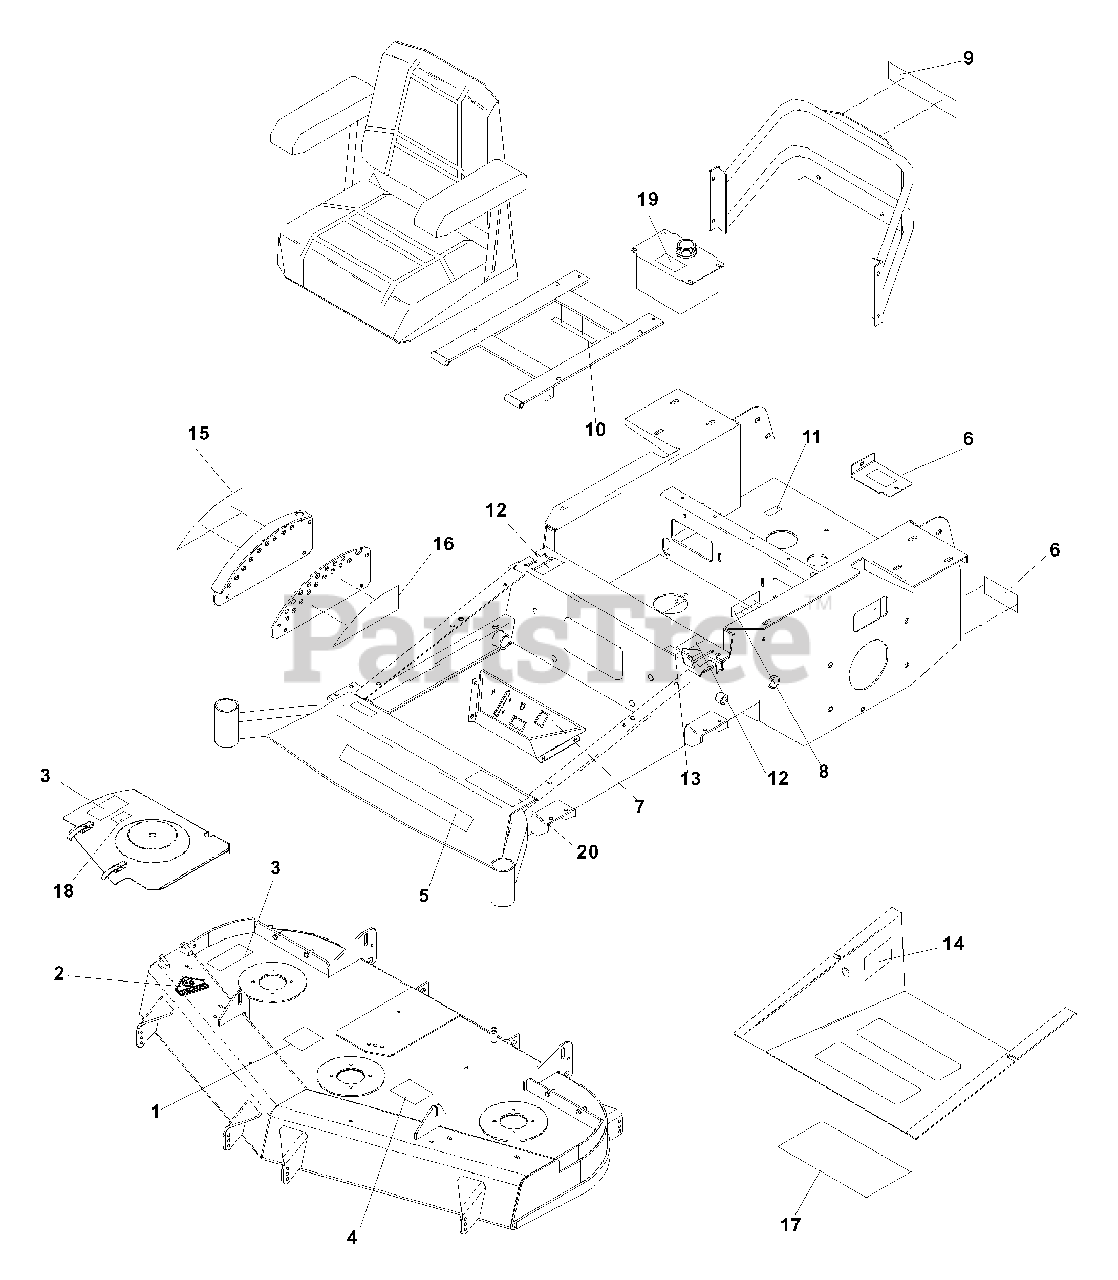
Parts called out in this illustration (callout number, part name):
1	DECAL, ANTI-SCALP
2	DECAL, DANGER
3	DECAL, WARNING
4	DECAL, BELT ROUTING
5	DECAL, HUSQVARNA
6	DECAL, BELT DRIVES
7	DECAL, CONSOLE
8	DECAL, RELAYS
9	DECAL, HUSQVARNA
10	DECAL, BATTERY
11	DECAL, PROP. 65
12	DECAL, MOTION CONTROL
13	DECAL, H.S.T.
14	DECAL, WARNING
15	DECAL, HEIGHT
16	DECAL, HEIGHT
17	DECAL, SERVICE
18	DECAL, NO STEP
19	DECAL, OIL TANK
20	DECAL, LZ6127
20	DECAL, LZ5227
20	DECAL, LZ6130
20	DECAL, LZ7230
